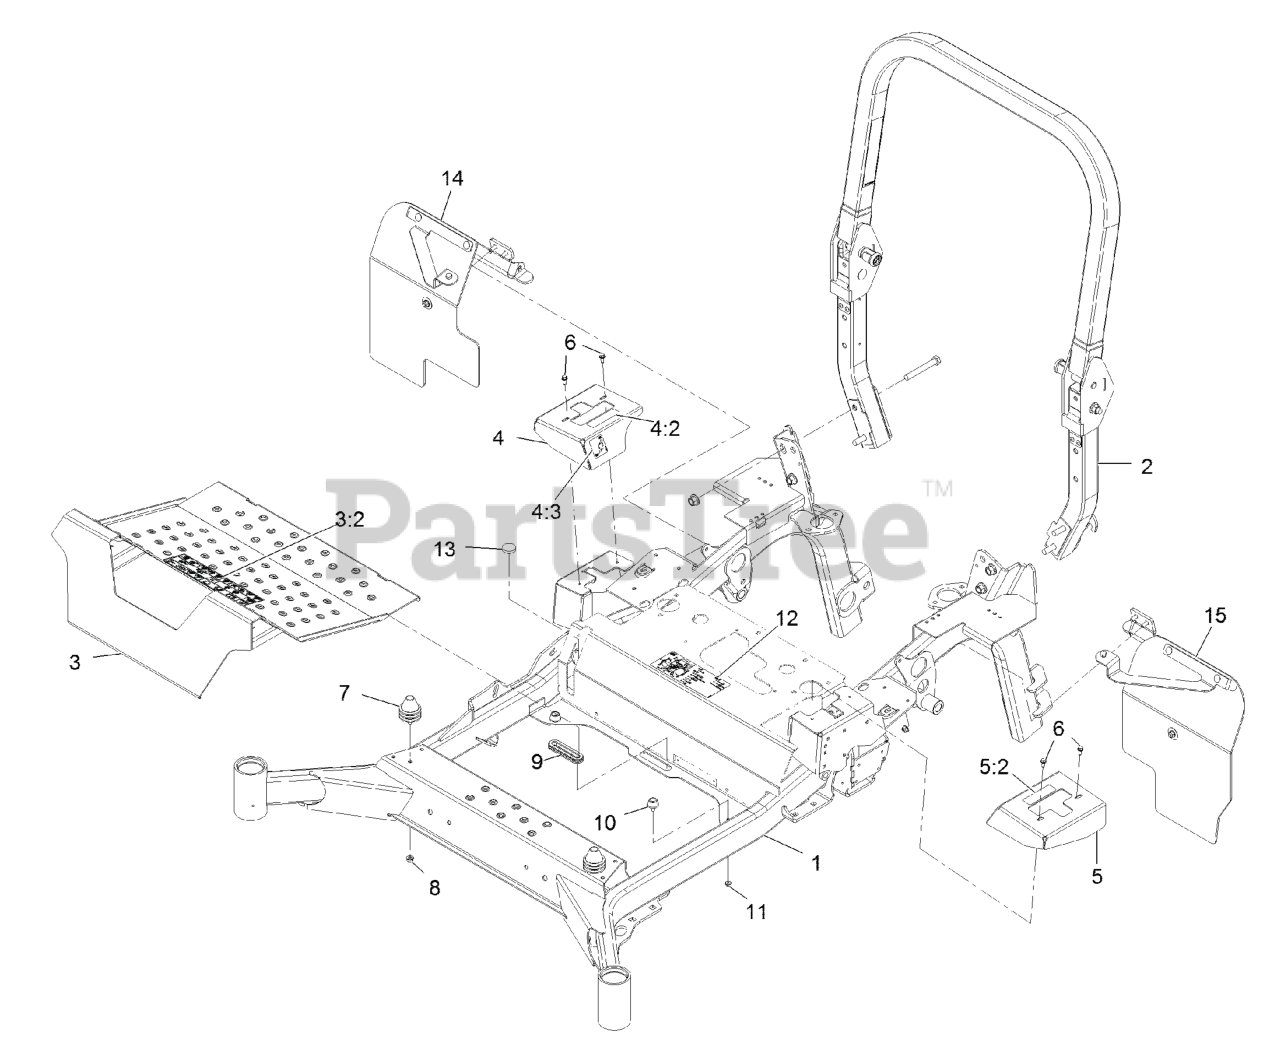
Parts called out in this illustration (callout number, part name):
1	Frame-Main
2	ROPS ASM
2	ASM, ROPS-7500D Diesel
3	PAN-FLOOR
3:2	DECAL-DANGER
4	COVER-MOTION CONTROL, RH
4:2	DECAL-CONTROL, MOTION
4:3	DECAL-PARK BRAKE, CE
5	COVER-MOTION CONTROL, LH
5:2	DECAL-CONTROL, MOTION
6	SCREW-HWH
7	ISOLATOR
8	NUT-HF, NI
9	GROMMET-RUBBER
10	BUMPER-RUBBER
12	DECAL-SERVICE AID
13	BUMPER-PUSH-IN, RUBBER
14	ASM, RH Mud Flap
15	ASM, LH Mud Flap
